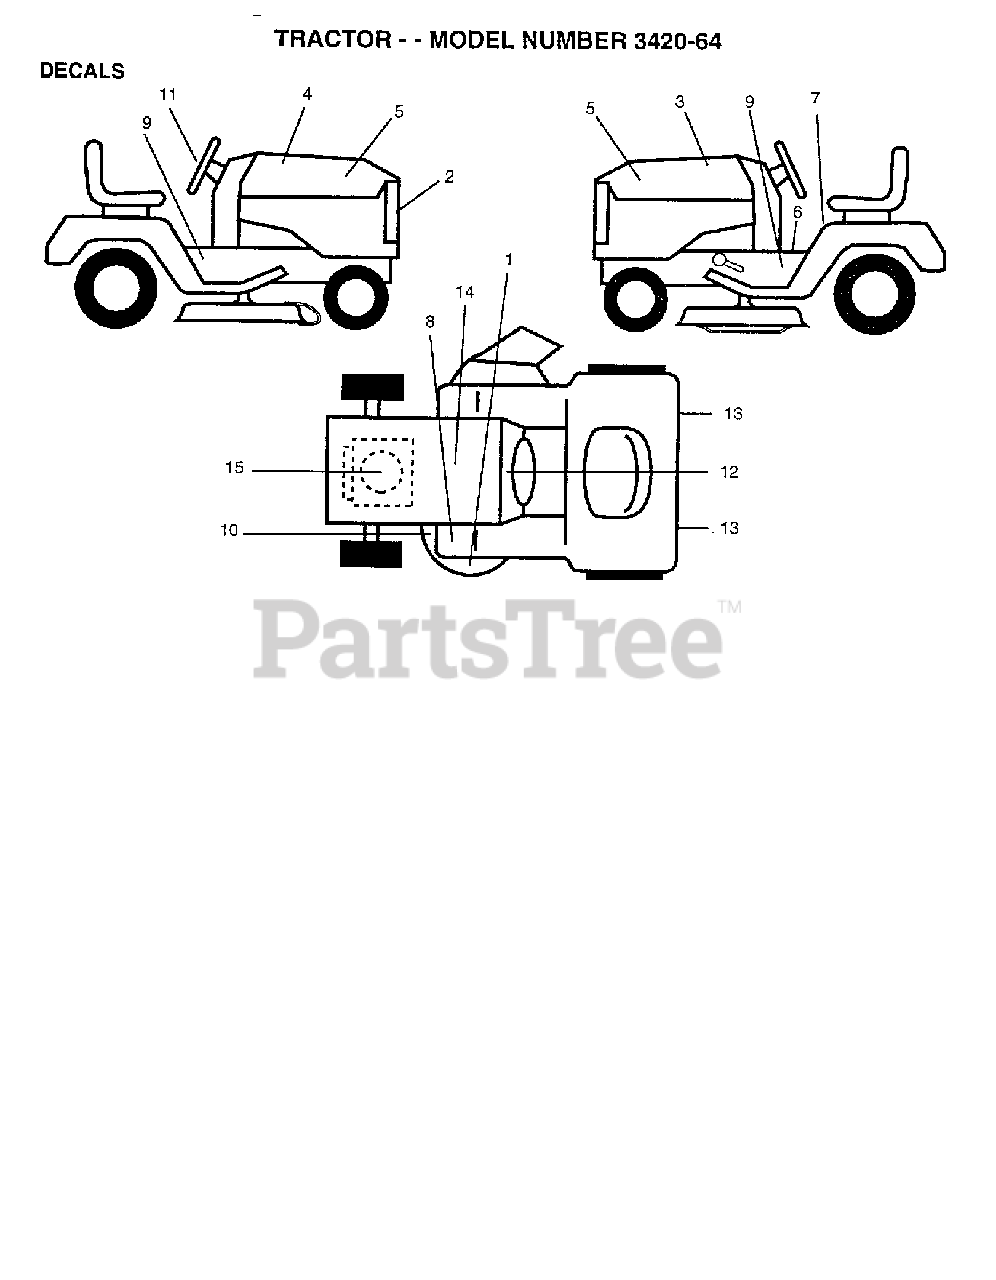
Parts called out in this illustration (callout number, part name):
2	Poulan TBD
3	Poulan TBD
4	Poulan TBD
5	Poulan TBD
6	DECAL PARK BRAKE
7	DECAL LT
9	Poulan TBD
10	DECAL V-BELT SCHEMATIC
11	Poulan TBD
13	REFLECTOR-TAIL YT
14	DECAL, BATTERY DANGER
15	Poulan TBD
